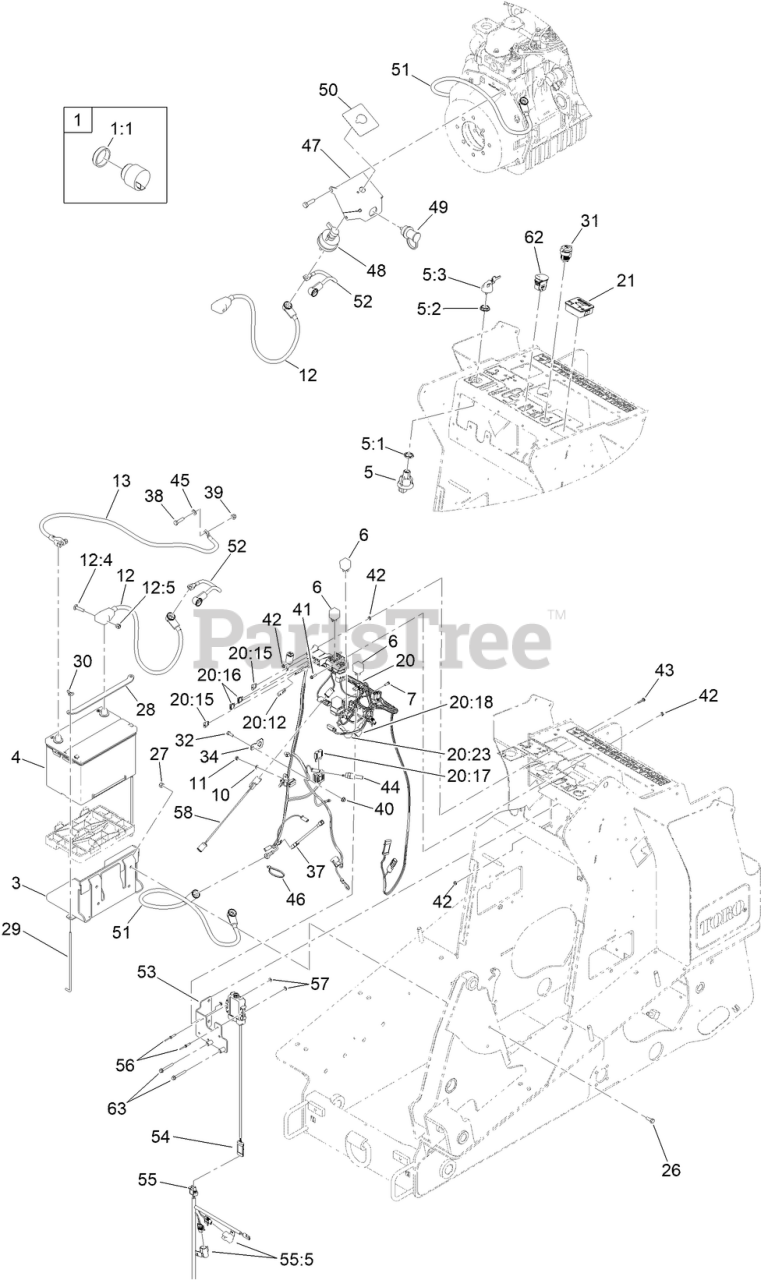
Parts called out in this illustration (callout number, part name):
1	AUDIO ALARM ASM
1:1	NUT-PLASTIC, KNURLED
3	TRAY-BATTERY
4	BATTERY
5	IGNITION SWITCH ASM
5:1	NUT-HEX
5:2	NUT-FACE, M22 (PLASTIC)
5:3	SET-KEY, IGNITION
10	WASHER-LOCK, SPRING
11	NUT-HEX
12	CABLE-BATTERY, POS ASM
12:4	BOLT-BATTERY CLAMP, 5/16-18 UNC
12:5	NUT-CLAMP, BATTERY
13	CABLE-NEGATIVE
20	HARNESS-WIRE, MAIN
20:15	FUSE-BLADE, 10 AMP
20:16	FUSE-BLADE, 15 AMP
20:17	FUSE-BLADE, 50 AMP
20:18	CAP-PLUG
21	MODULE-HOUR METER
26	SCREW-HH
27	NUT-LOCK, NI
28	STRAP-HOLD DOWN, BATTERY
29	ROD-HOLD DOWN, BATTERY
30	NUT-WING
31	RECEPTACLE-12V
32	SCREW-HH
34	CLIP-FUSE
37	HARNESS-LINK, FUSIBLE
38	SCREW-HH
39	NUT-HF, NI
40	NUT-HF
41	SCREW-HWH
42	NUT-KEPS
43	SCREW-HWHTF
44	SWITCH-TEMP
45	WASHER-PLAIN
46	TIE-CABLE
47	MOUNT-REMOTE TERMINAL
48	SWITCH-DISCONNECT, MASTER
49	STUD-JUMPER, POSITIVE
50	DECAL-BATTERY DISCONNECT
51	CABLE-BATTERY, POSITIVE
52	CABLE-BATTERY, POSITIVE
54	GPS ASM
55	HARNESS-WIRE, GPS
55:5	COVER-FUSE, SINGLE
56	RIVET-POP
57	WASHER-PLAIN
58	HARNESS-WIRE
62	SWITCH-ROCKER, ON-NONE-(ON)
63	SCREW-HHF
